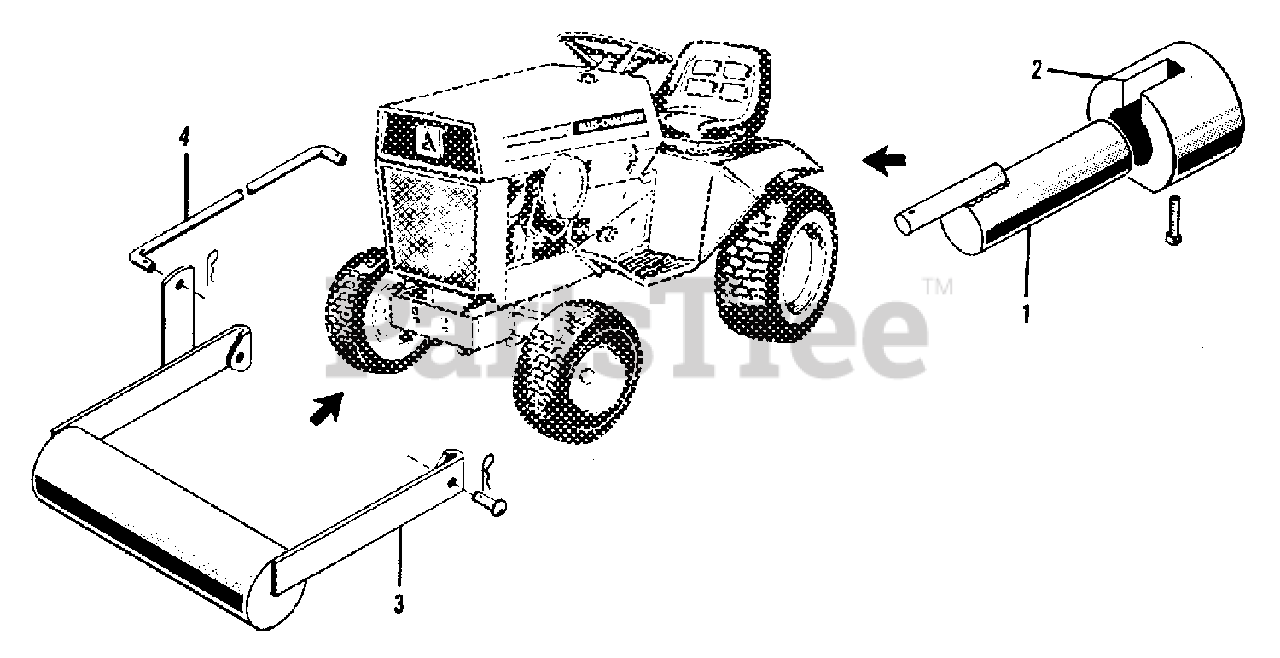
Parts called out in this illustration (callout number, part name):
1	**WEIGHT, Rear Counter**(See MACHINERY)
1	PIN, Round Head
1	PIN, Quick
2	**WEIGHT, Rear Auxiliary
3	**WEIGHT, Front counter**(See MACHINERY)
3	PIN, Round Head
3	PIN, Quick
4	ROD, Lift (Front Weight)
4	PIN, Quick
